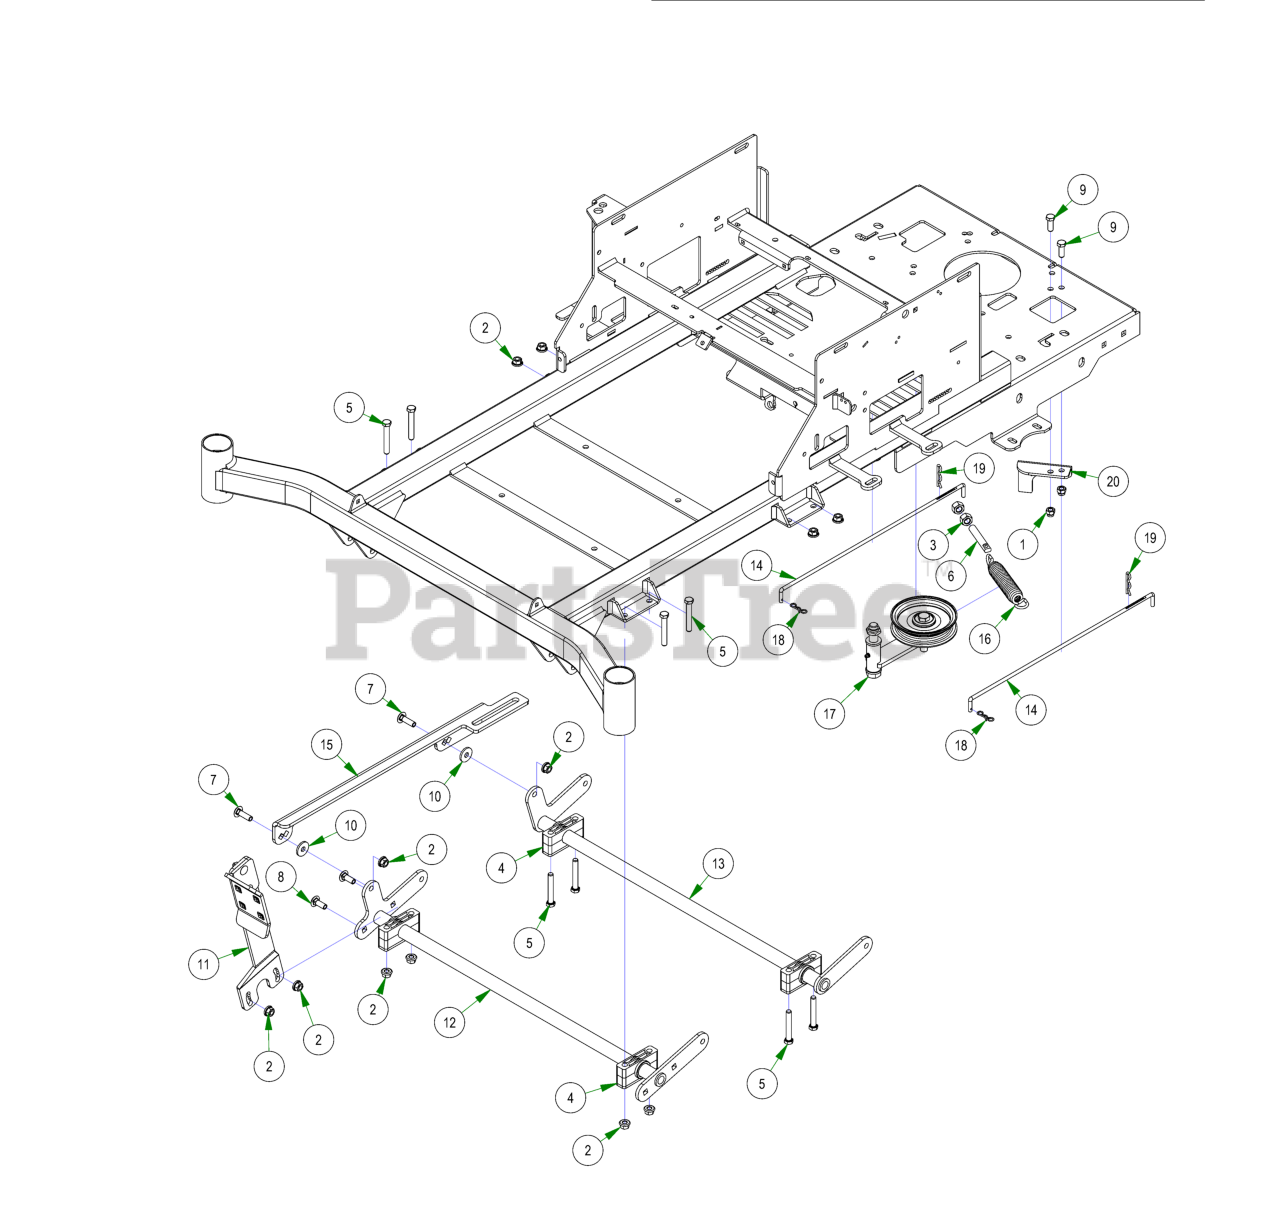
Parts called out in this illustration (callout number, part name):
1	3/8-16 NYLON INSERT LOCKNUT ZINC
2	3/8-16 NYLON INSERT FLANGE LOCKNUT (GR.F) ZINC
3	1/2-13 HEX NUT ZINC
4	Pillow Block Kit
5	3/8-16 X 2-1/2 HEX CAP SCREW (GR.5) ZINC
6	All Thread
7	3/8-16 X 1-1/4 CARRIAGE BOLT ZINC
8	3/8-16 X 1 CARRIAGE BOLT (GR.5) ZINC
9	3/8-16 X 1 GR 5 Hex Bolts Zinc
10	.390 ID X 1.12 OD X .125 THK FLAT WASHER NYLON
11	Foot Pedal Assembly
12	Actuator Bar Front- 2017 MZ/ZT
13	Actuator Bar Rear- 2017 MZ/ZT
14	Neutral Rod
15	2017 MZ/ZT Actuator Linkage
16	Deck Idler Spring
17	ZT Pump Idler
19	Neutral Rod Clip
20	2017 MZ Clutch Stop
21	2024 MZ-Avenger 54-60 Frame
